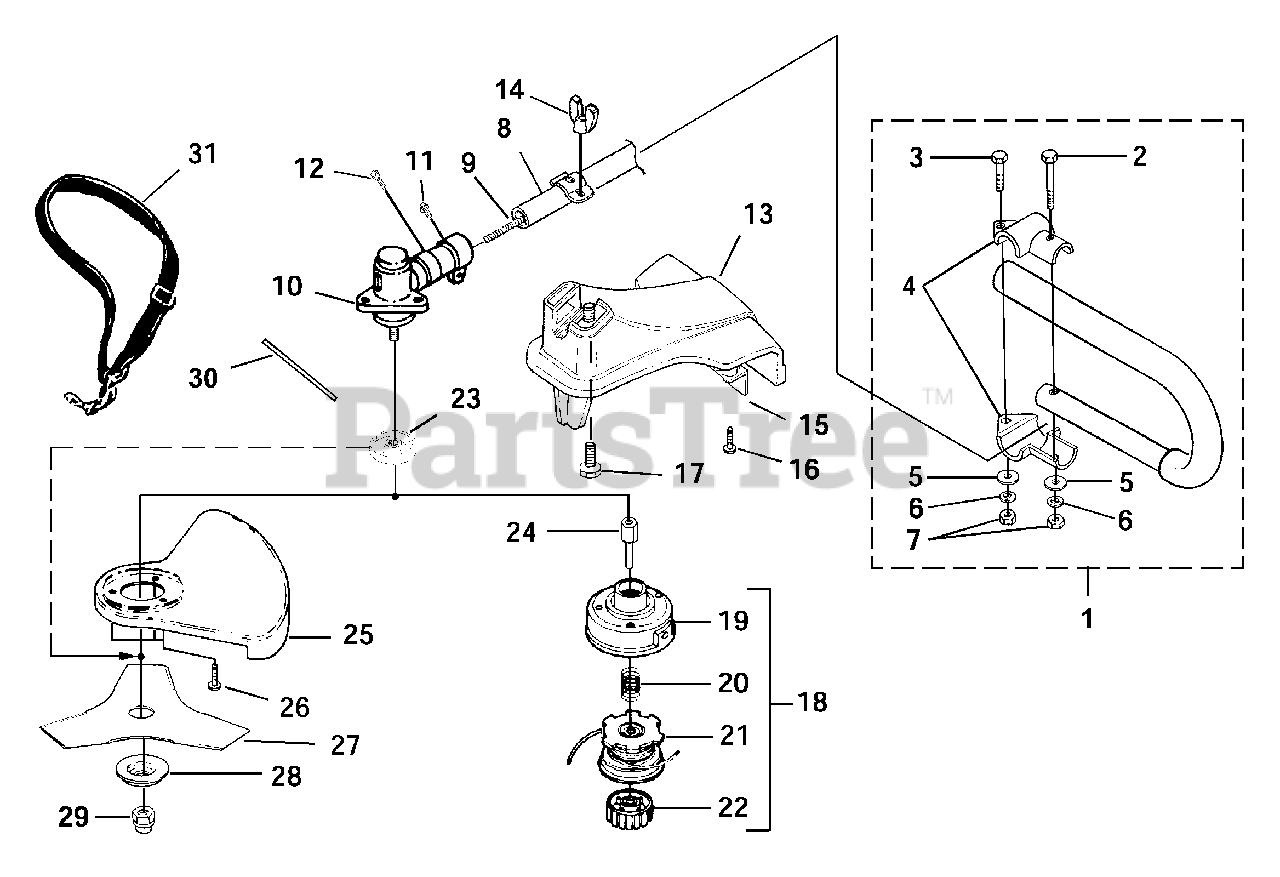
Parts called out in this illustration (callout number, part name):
1	HANDLE ("J")
2	SCREW-Hex Hd. (1/4-20 X 1 1/2")
3	SCREW-Hex Hd. (1/4-20 X 1")
4	CLAMP-Handle Bar
5	WASHER-Flat (1/4")
6	WASHER-Lock (1/4")
7	NUT-Hex (1/4-20)
8	DRIVESHAFT HOUSING
9	FLEXSHAFT
10	GEAR HEAD
11	Screw, Cap Hd. (1/4-20 X 7/8")
12	Screw-Hex Hd. (10-24 x 1/2")
13	GRASS DEFLECTOR KIT
14	WING NUT
15	BLADE-Cut-Off
16	SCREW, Thread Form. (10-24 X 3/4")
17	SCREW-Square Head
18	STRINGHEAD-Complete (.095")
19	HOUSING & EYELET (Dual Line)
20	SPRING-Compression
21	SPOOL & STRING (.095")
22	RETAINER-Spool (L.H. Thread, Red)
23	WASHER-Flanged
24	ADAPTER-Shaft
25	BLADE GUARD
26	SCREW
27	BLADE-Tri-Arc(TM)
28	WASHER-Cupped (Lower)
29	NUT-Hex (L.H.)
30	TOOL-Holding Pin
31	HARNESS
